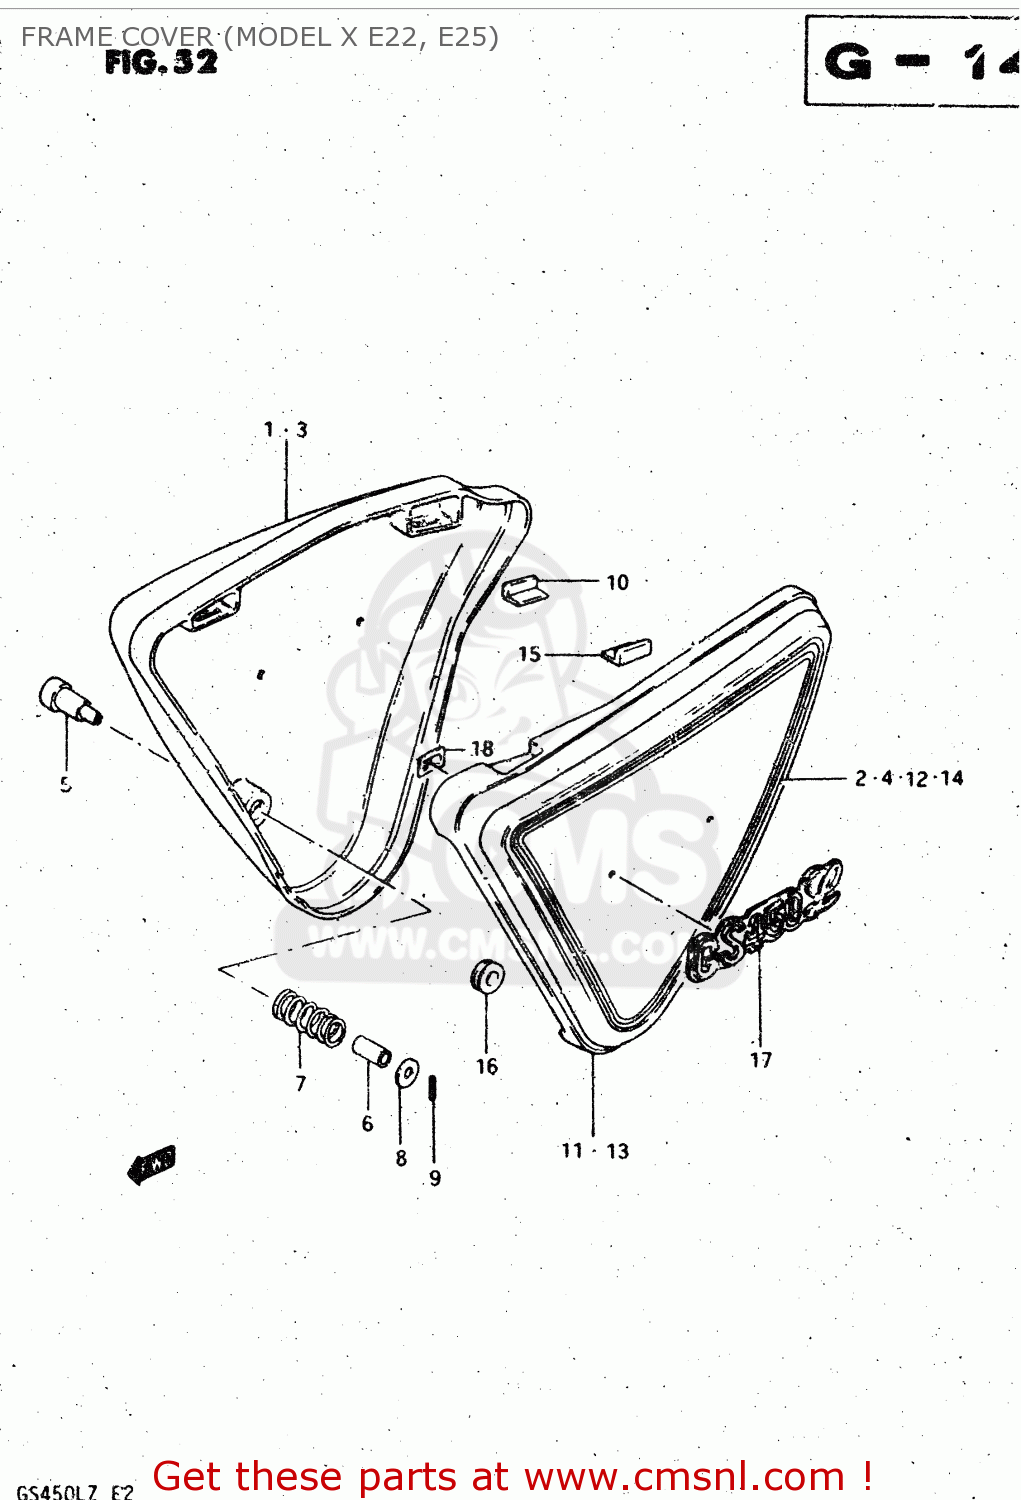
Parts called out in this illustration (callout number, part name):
1	COVER,FRAME,RIGHT
2	TAPE SET,FRAME COVER
3	COVER,FRAME,RIGHT
4	TAPE SET,FRAME COVER,RIGHT
5	KNOB,FRAME COVER,R
6	SPACER(14.9X17.3X13.5)
7	SPRING
8	WASHER (6.5X24X1.6)
9	PIN,SPRING(2.5X18)
10	CUSHION,FRAME COVER
11	COVER,FRAME,LEFT
12	TAPE SET,FRAME COVER
13	COVER,FRAME,LEFT
14	TAPE SET,FRAME COVER,LEFT
15	CUSHION,FRAME COVER
16	CUSHION
17	EMBLEM
18	NUT
